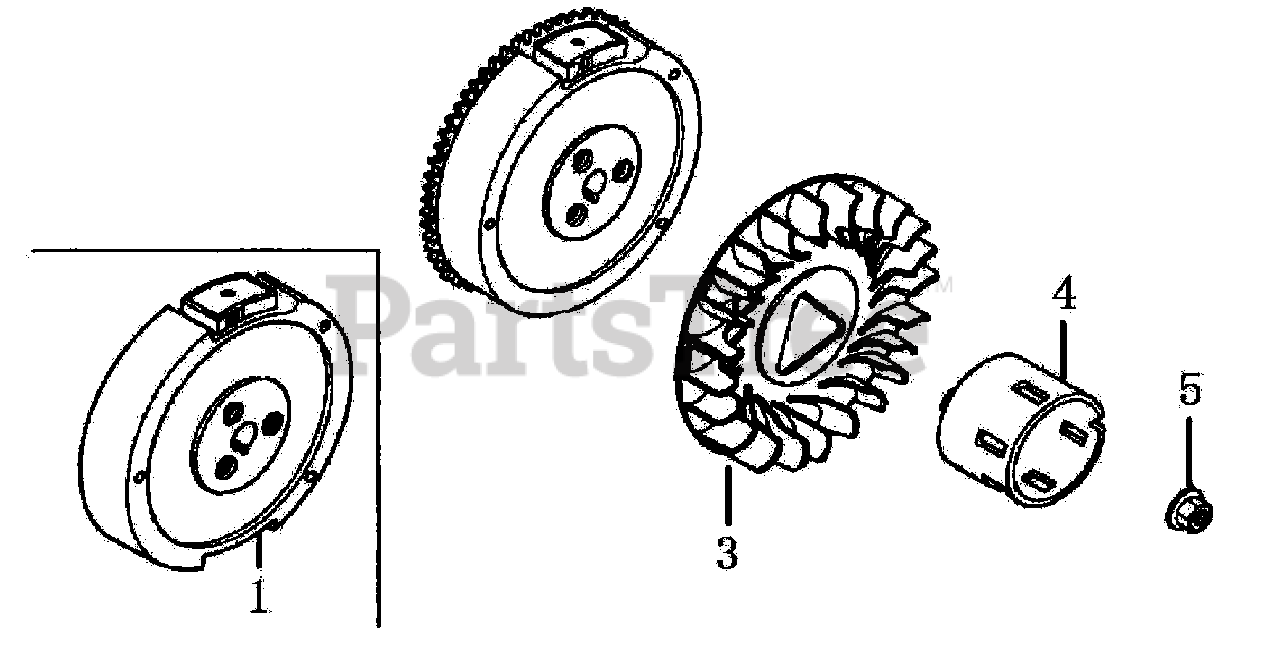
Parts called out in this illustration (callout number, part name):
1	FLYWHEEL COMP.
3	FAN, COOLING
4	PULLEY, STARTER
5	NUT, SPECIAL
